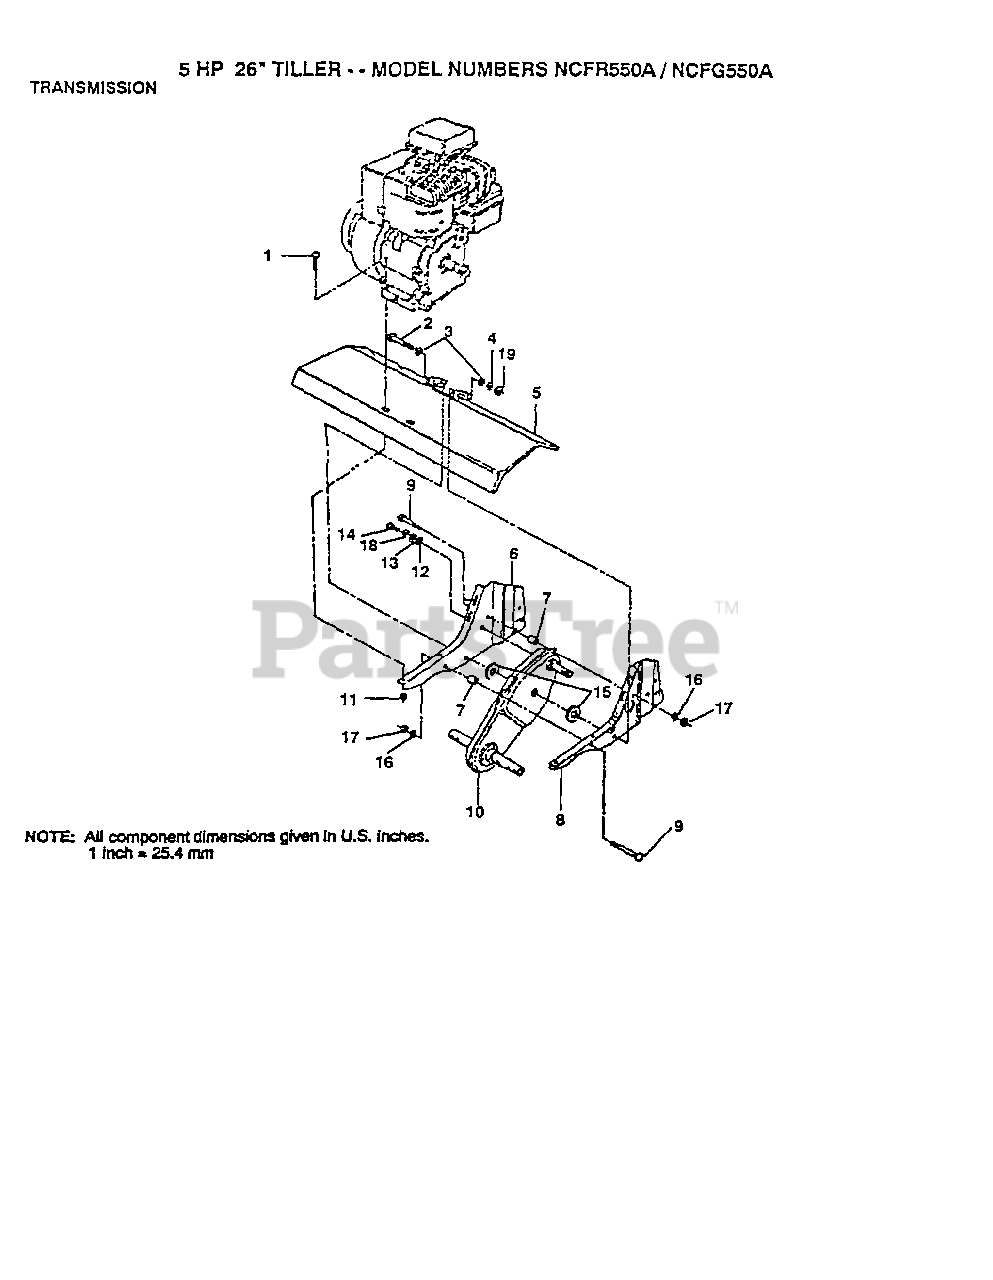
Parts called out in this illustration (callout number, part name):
1	BOLT.HEX.5/16-1.5
2	BOLT.3/8-24X3.75
3	WASHER
4	LOCKWASHER
7	SPLIT SPACER RT
8	BRACKET.ENG.LH.
12	WASHER
13	WASHER
14	BOLT
16	LOCKWASHER
17	NUT.HEX.5/16-18
18	LOCKWASHER
19	GRIPCO NUT
